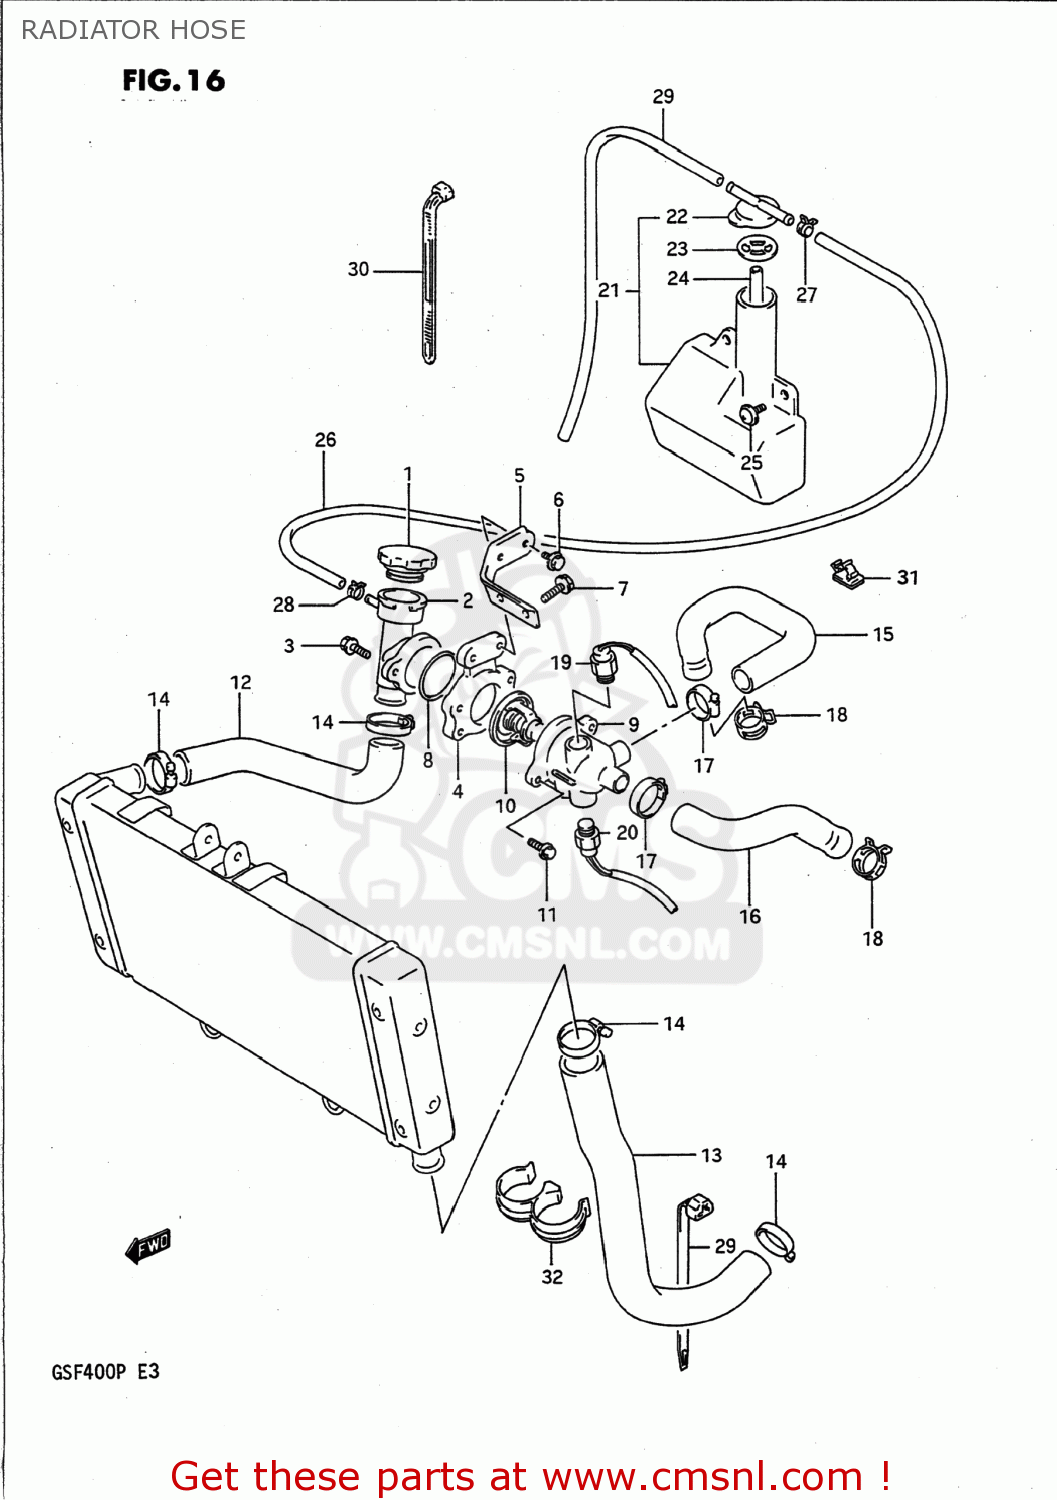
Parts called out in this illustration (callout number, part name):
1	CAP,RADIATOR 1.1
2	CONDUCTION,RADIATOR
3	BOLT 6X16
4	BRACKET,CONDUCTION
5	BRACKET,CONDUCTION BRAKE
6	BOLT
7	BOLT 6X20
8	O RING(D:2.4,ID:43.2)
9	CONNECTOR,THERMOSTAT INLET
10	THERMOSTAT,WATER
11	BOLT 6X20
12	HOSE,RADIATOR INLET
13	HOSE,RADIATOR OUTLET NO.1
14	CLAMP
15	HOSE,RADIATOR JOINT NO.1
16	HOSE,RADIATOR JOINT NO.2
17	CLAMP
18	CLAMP
19	SWITCH ASSY,WATER TEMP
20	SWITCH,RADIATOR FAN
21	TANK ASSY,RESERVOIR
22	CAP,WATER RESERVOIR TANK
23	RUBBER,WTR RSV TANK CAP
24	HOSE (7X12.1X600)
25	SCREW(6X16)
26	HOSE,RESERVOIR TANK INLET
27	CLIP
28	CLIP
29	HOSE
30	CLAMP(L:235)
31	CLAMP
32	CLAMP
